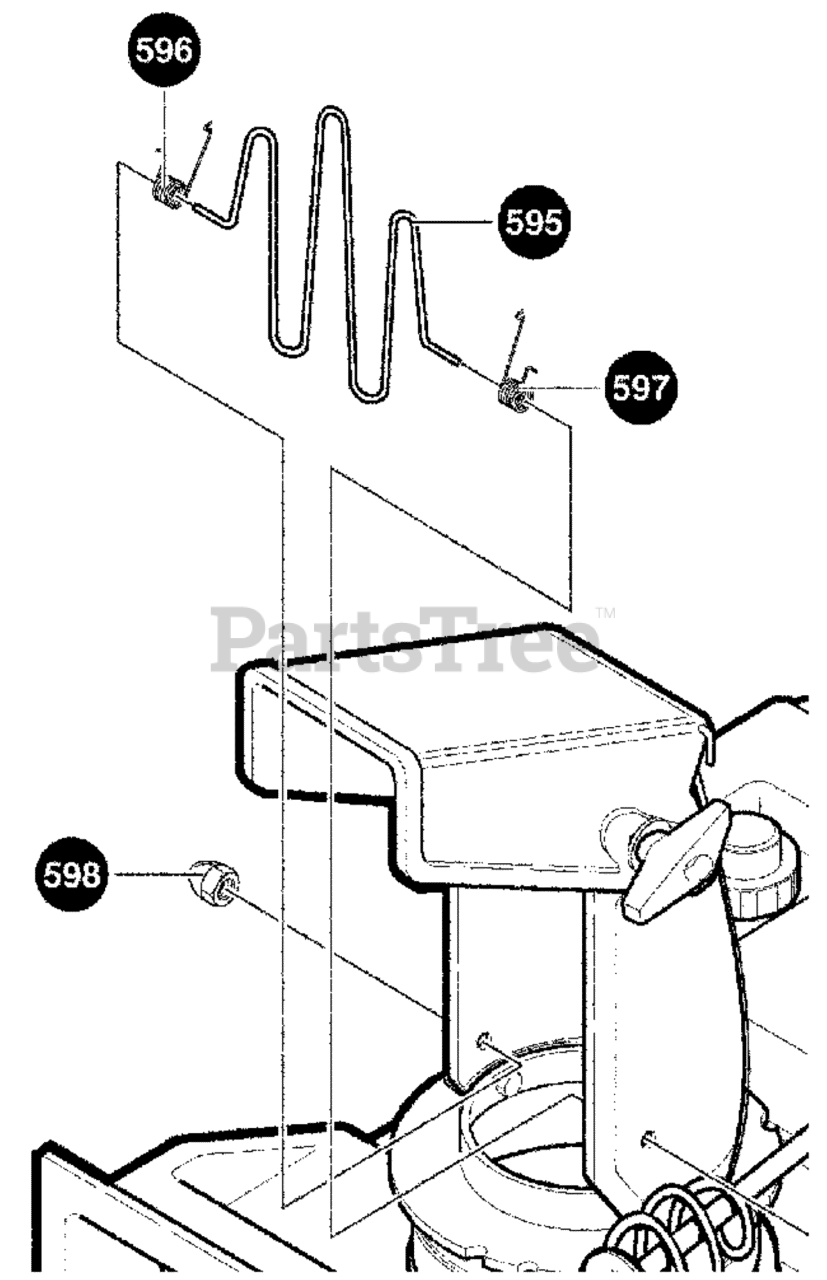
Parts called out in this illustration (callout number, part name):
595	GUARD, WIRE CHUTE
596	SPRING, TORSION
597	SPRING, TORSION
598	NUT, ACORN
